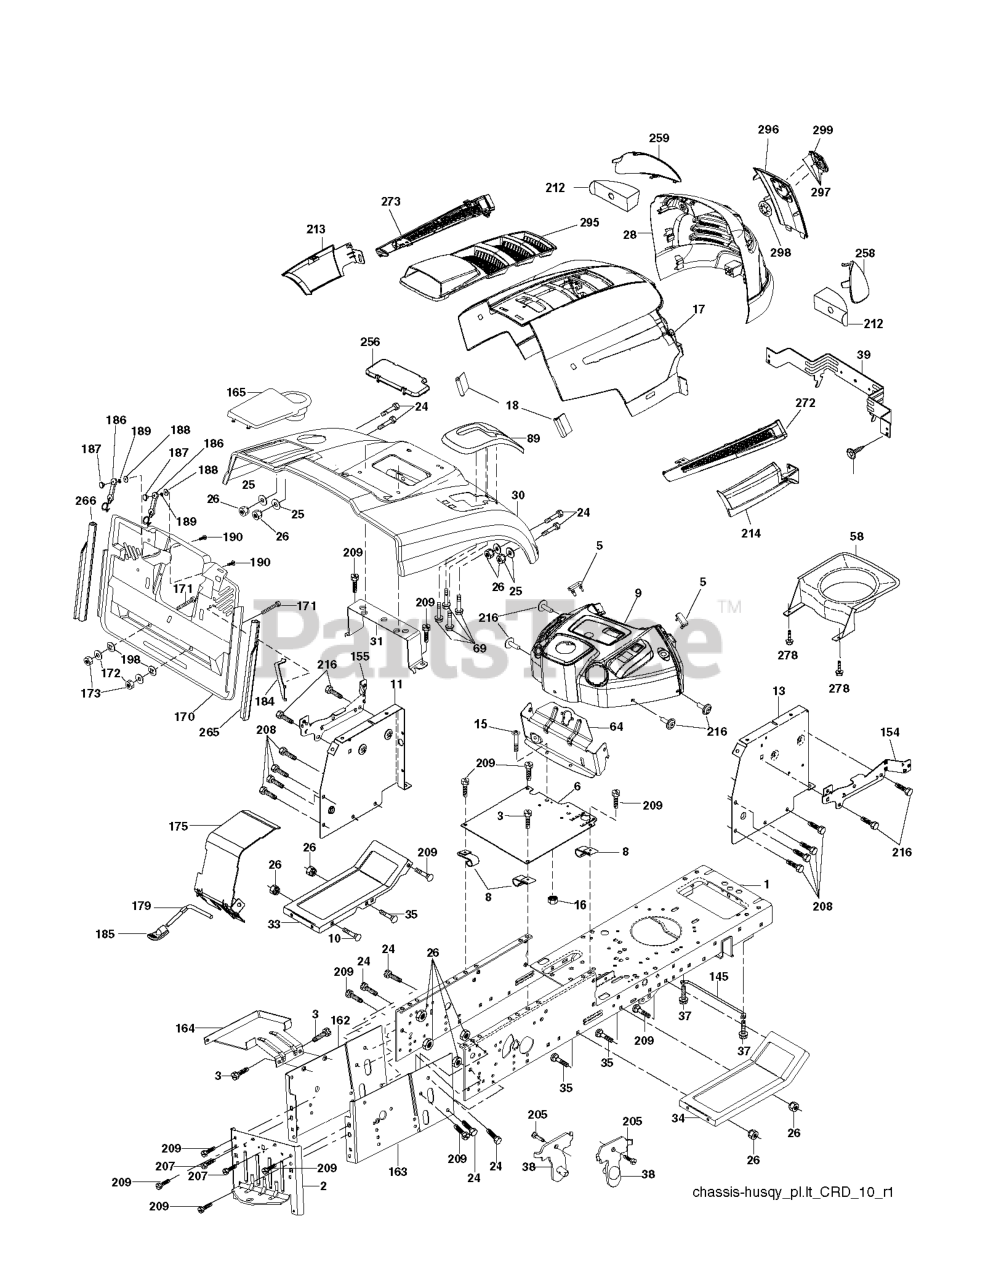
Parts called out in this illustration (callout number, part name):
2	DRAWBAR
3	SCREW 3/8-16X3/4
5	BUMPER DASH
6	PLATE
8	CLIP,INSULATOR
10	BOLT D
11	PANEL.DASH.LH.LTX
13	PANEL ASM, DASH RH
15	Screw, Machine, Truss Head 5/16-18 UNC x 3/4
16	NUT
17	HOOD
18	BUMPER.HOOD.TEX.HUSQVARNA
25	WASHER
26	NUT
28	RP GRILLE/LENS ASM.
30	CONSOLE.CRD.AUTO.GRY
31	BRACKET SUPPORT FENDER
33	FOOTREST PNT LH
34	FOOTREST PNT RH
37	Screw 5/16-18 x 1/2 Hex, Self Tapping 5/16-18 x 1/2
38	BRACKET ASM PIVOT MOWER REAR
39	BRACKET PIVOT
69	SCREW.HI-LO.CONSOLE
89	CONSOLE.CRD.AUTO.GREY.2005
145	ROD.PIVOT.HOOD
162	BRACKET
163	BRACKET EXTEN CHASSIS RH CRD
165	RP.COVER.BATTERY.CRD.GREY
172	WASHER
175	DOOR TRAP
179	ROD PIVOT FBI
184	BRACKET.ACTUATOR.BAGGER.SRD
186	LATCH ASSY
187	WELDNUT
189	LOCKWASHER #10
190	SCREW
207	SCREW, 5/16-18 X 1/2
208	SCREW 3/8-16X1/2
209	SCREW, 3/8-16X3/4
212	INSERT REFLECTIVE
213	SKIRT SIDE LH
214	SKIRT SIDE RH
216	SCREW HEXWSHR 1/4-20X3/4
256	COVER FENDER CRD
258	LENS.HUSQVARNA LT.RH
259	LENS.HUSQVARNA LT.LH
265	SEALING
266	SEALING
272	VENT SIDE HOOD RH
273	VENT SIDE HOOD LH
278	SCREW
295	VENT TOP HOOD
296	TRIM
297	CLIP.RETAINER.TINNER.
298	NUT PUSH M
299	RP LOGO
